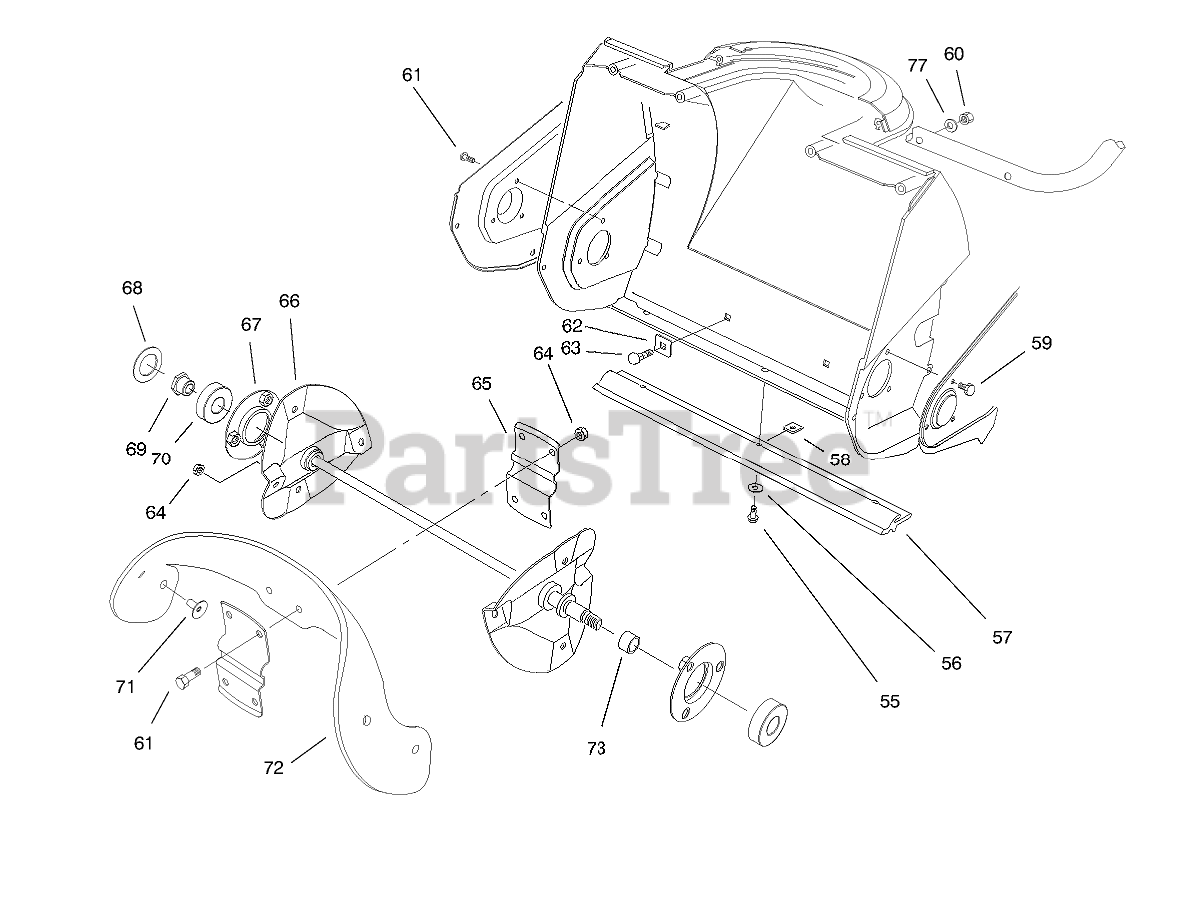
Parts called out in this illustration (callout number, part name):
55	SCREW-HWHTF
56	WASHER-FLAT
57	SCRAPER
58	NUT-CLIP, U
59	SCREW-HH
60	NUT-LOCK, NI
61	SCREW-HHF
62	WASHER-SQUARE
63	SCREW-CARR
64	NUT-LOCK, NI
65	Support-Rotor
66	Rotor
67	FLANGE BEARING ASM
68	WASHER-RUBBER
70	BEARING-BALL
71	SCREW
72	BLADE-ROTOR
73	SPACER
77	WASHER
